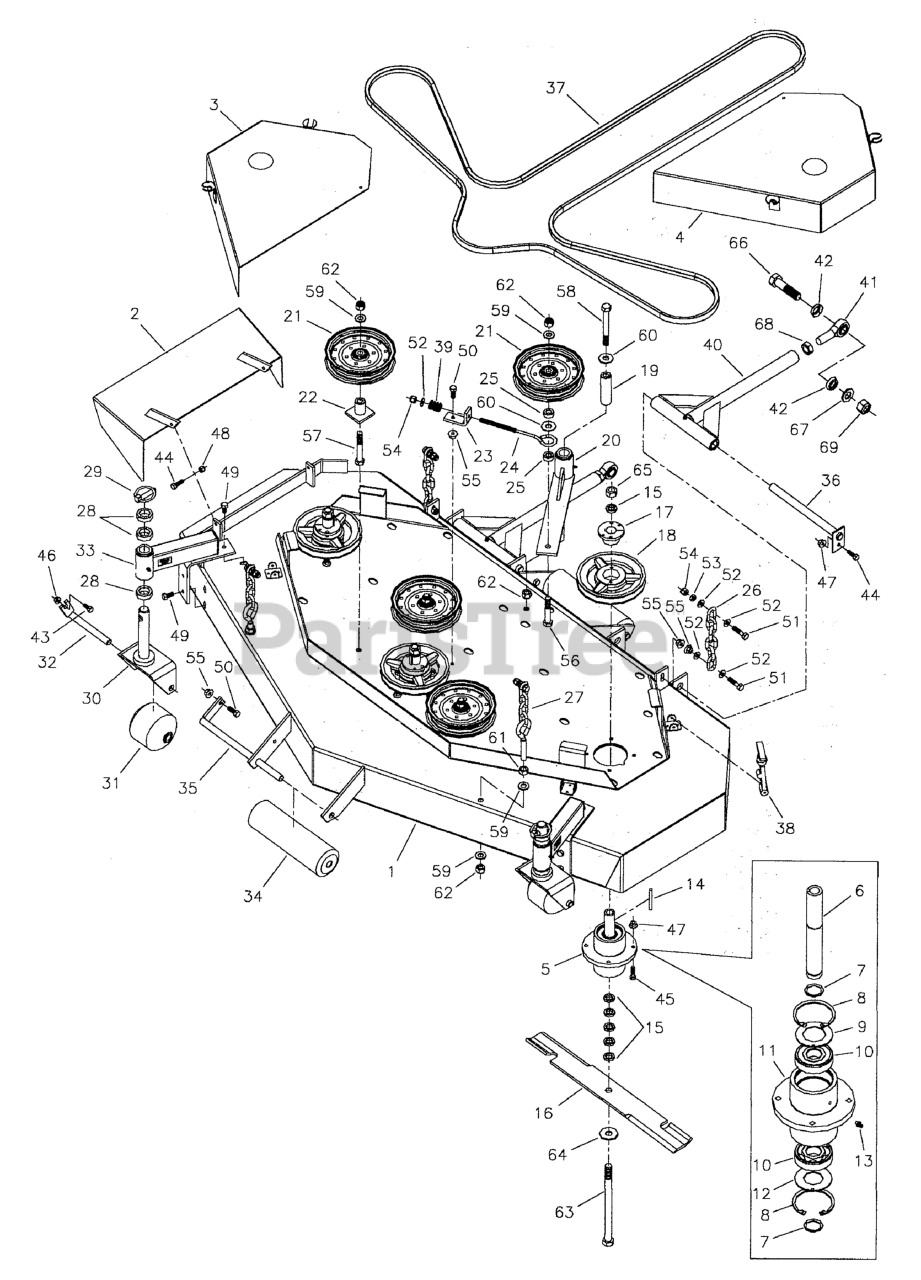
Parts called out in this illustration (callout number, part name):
1	DECK SHELL W/DECALS, 61, Z61
2	CHUTE, DISCHARGE WELDMENT
3	GUARD, Deck, Right
4	GUARD, Deck, Left
5	SPINDLE ASSEMBLY, Complete
6	SPINDLE SHAFT
7	SNAP RING, External
8	SNAP RING, Internal
9	SPINDLE WASHER, Top
10	BEARING
11	SPINDLE HOUSING
12	SPINDLE WASHER, Bottom
13	GREASE FITTING
14	KEY, 1/4 SQ. X 2-1/2
15	SPACER, .63 x 1.06 x .23
16	MOWER BLADE, 21"
17	BUSHING, Tapered Hub
18	PULLEY, Spindle
19	SPACER, .52 x 1.00 x 3.50
20	IDLER ARM ASSEMBLY
22	IDLER PULLEY MOUNT
23	SPRING ANCHOR
24	EYEBOLT, 3/8" x 8"
25	SPACER, .52 x 1.00 x .44
26	CHAIN, 6 LINKS
27	HANGER, FRONT DECK - 4 LINK, 5.5" EB
28	SPACER, 1.02 x 1.56 x .50
29	PIN, Lynch
30	CASTER YOKE
31	ROLLER, Caster
32	CASTER ROLLER PIN
33	ARM, DECK CASTER ASSEMBLY
34	ROLLER
37	BELT, 5V, 175.90EL, LG ARAMID, WRPD, RC
38	RUBBER LATCH
39	SPRING, Compression
40	ASSM, DECK PUSHER BAR
41	BALL JOINT, 3/4-16 Male
42	ROD END SEAL
43	BOLT, 5/16-18 X 3/4 GD5
44	BOLT, 5/16-18 X 1 GD5 YZ
45	BOLT, 5/16-18 x 1-1/4
46	NUT, 5/16-18 HEX SERRATED FLANGE (SMALL)
47	NUT, 5/16-18 HEX SERRATED FLANGE (LARGE)
48	NUT, 5/16-18 Hex Nylon Lock
49	BOLT, 3/8-16 X 3/4" GD5 CZ
50	BOLT, 3/8-16 X 1" GD5 CZ
51	BOLT, 3/8-16 X 1-3/4" GD5 CZ
52	WASHER, 3/8 SAE
53	NUT, 3/8-16 HEX JAM
54	NUT, 3/8-16 HEX NYLON LOCK
55	NUT, 3/8-16 Hex Serrated Flange
56	BOLT, 1/2-13 X 3" GD5 CZ
57	BOLT, 1/2-13 X 3-1/2, HEX HD, GD5, CZ (SV)
58	BOLT, 1/2-13 x 4-1/2
59	WASHER, 1/2 SAE
60	WASHER, 1/2" USS
61	NUT, 1/2-13 Hex
62	NUT, 1/2-13 HEX NYLON LOCK
63	BOLT, 5/8-11 x 9-1/2
64	WASHER, 5/8" USS
65	NUT, 5/8-11 Hex
66	BOLT, 3/4-16 x 3
67	WASHER, 3/4 SAE
68	NUT, 3/4-16 Hex Jam
69	NUT, 3/4-16 Hex Nylon Lock
